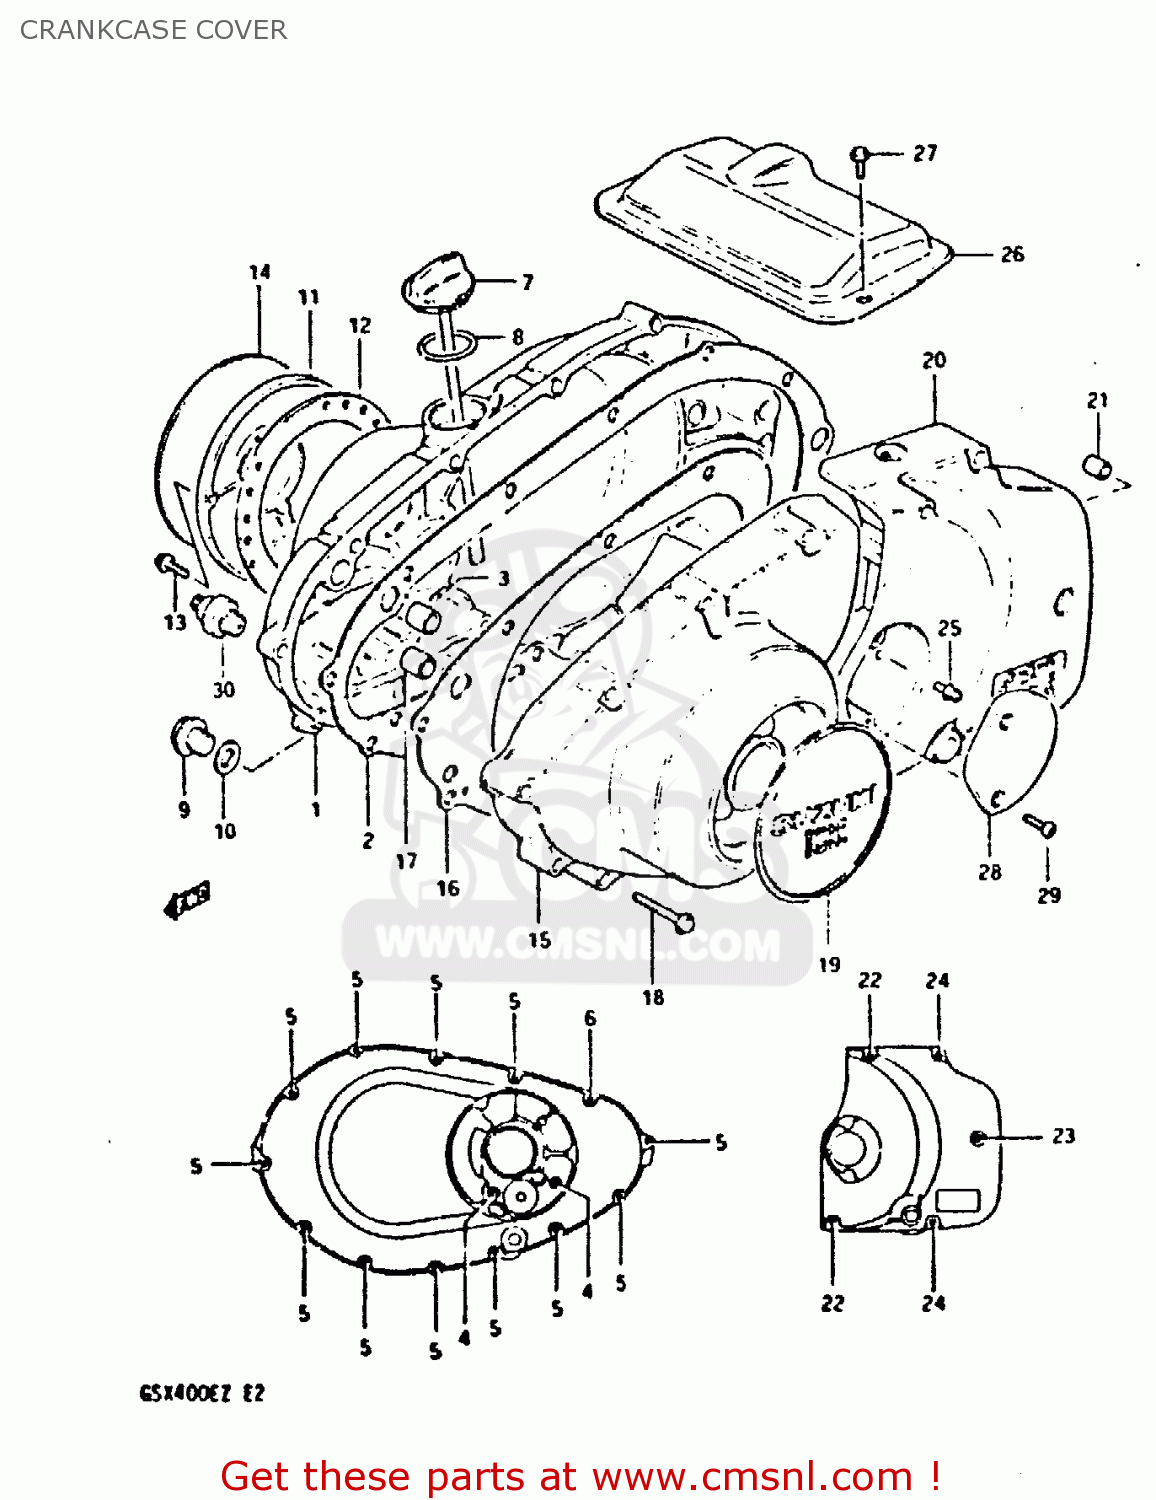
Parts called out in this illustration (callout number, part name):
1	COVER,CLUTCH
2	GASKET,CLUTCH COVER (MCA)
3	PIN
4	BOLT (6X55)
5	BOLT (6X35)
6	BOLT
7	GAUGE,OIL LEVEL
8	O-RING
9	PLUG (14X12)
10	GASKET(14X19.2X2) (NAS)
11	COVER,CONTACT BREAKER
12	GASKET,CONTACT BREAKER COVER (NAS)
13	BOLT 5X16
14	EMBLEM
15	COVER,MAGNETO
16	GASKET,MAGNETO COVER (MCA)
17	PIN
18	BOLT (6X35)
19	EMBLEM
20	COVER,ENGINE SPROCKET
21	PIN
22	BOLT (6X65)
23	BOLT (6X50)
24	BOLT (6X40)
25	NIPPLE
26	COVER,STARTER MOTOR
27	BOLT (5*8)
28	CAP,CLUTCH RELEASE ADJUST
29	SCREW 5X12
30	SWITCH ASSEMBLY
